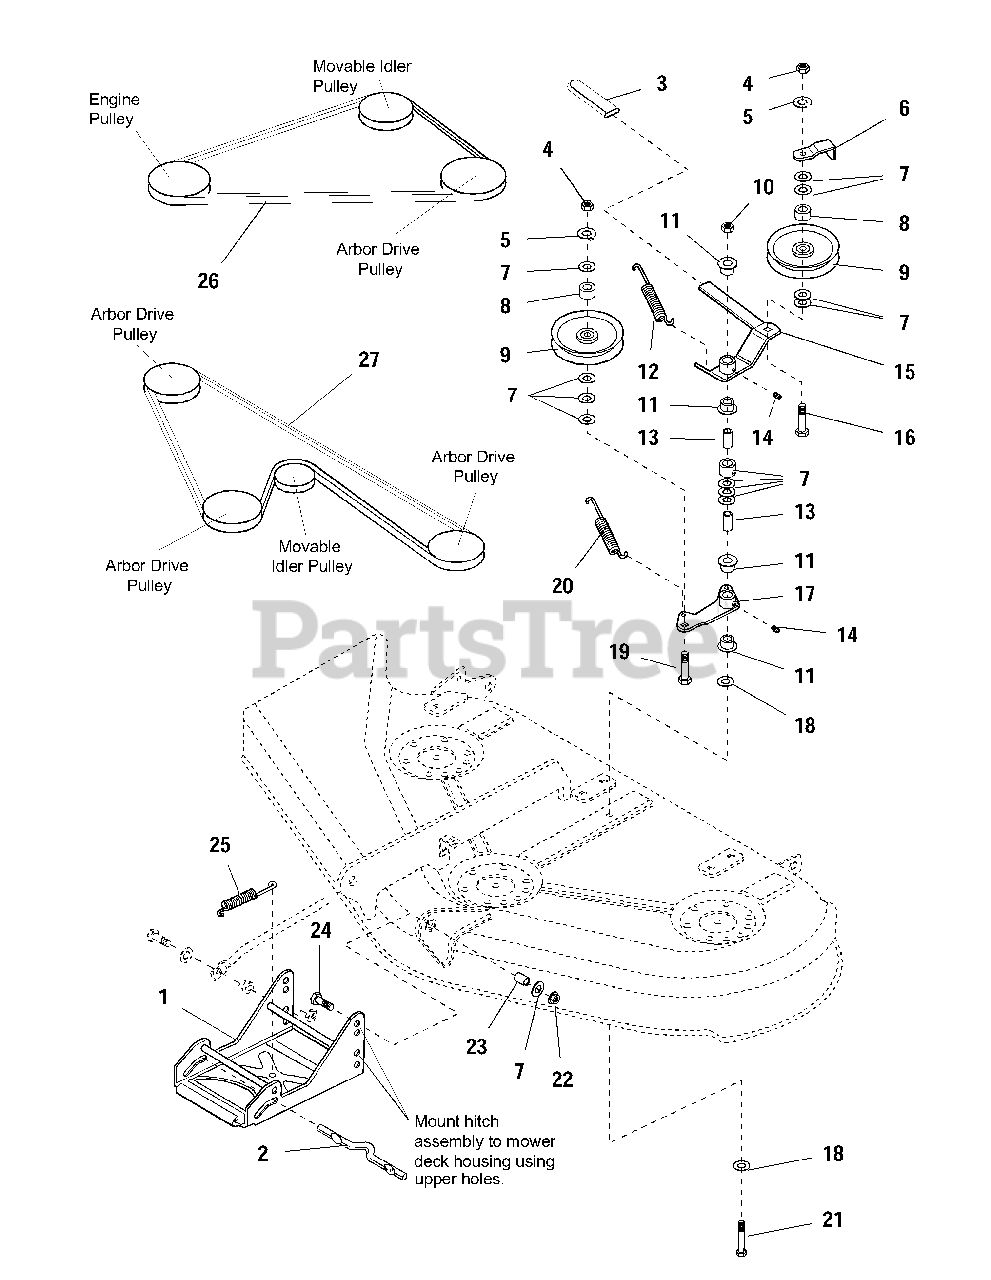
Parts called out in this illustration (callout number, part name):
1	HITCH ASSEMBLY
3	GRIP, Lever
4	NUT, Hex, 3/8-16
5	LOCKWASHER, 3/8
6	BELT STOP, Idler
7	WASHER, Plain, 13/32
9	PULLEY, Idler
10	NUT, Hex Flange, 2-Way Lock, 3/8-16
14	FITTING, Grease
15	LEVER ASSEMBLY, Idler
16	CARRIAGE BOLT, 3/8-16 x 2
17	LEVER ASSEMBLY, Idler Arm
18	WASHER, 3/8
19	CARRIAGE BOLT, 3/8-16 x 1-1/2
21	CAPSCREW, Hex Hd, 3/8-16 x 3-1/2
22	NUT, Hex Nylon Lock, 3/8-16
24	CAPSCREW, Hex Hd, 3/8-16 x 1-1/2
25	SPRING
26	V-BELT, Arbor Drive, 44" Deck
27	V-BELT, Mower Drive, 44" Deck
